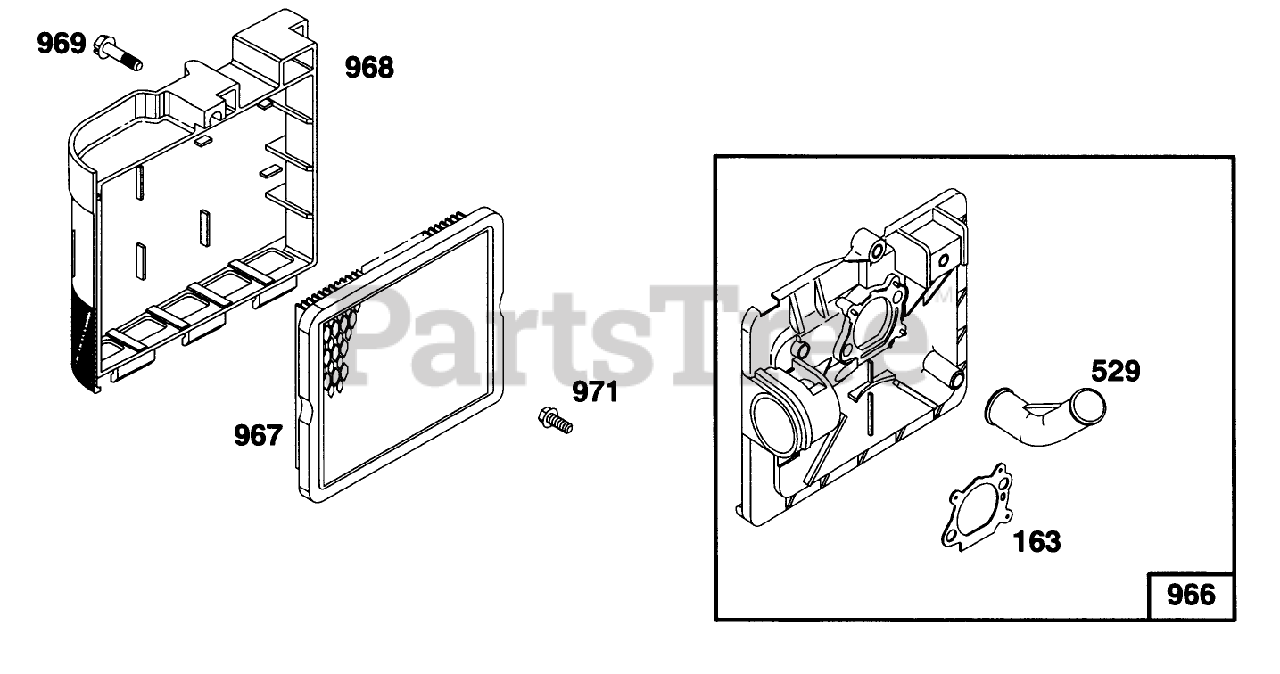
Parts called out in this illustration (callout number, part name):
163	Gasket-Cleaner, Air
529	Grommet
966	Base-Primer, Air Cleaner
967	Filter-Air Cleaner, Cartridge
968	Air Cleaner Cover
969	Screw-Cover Mt.
971	Screw-Air Cleaner
